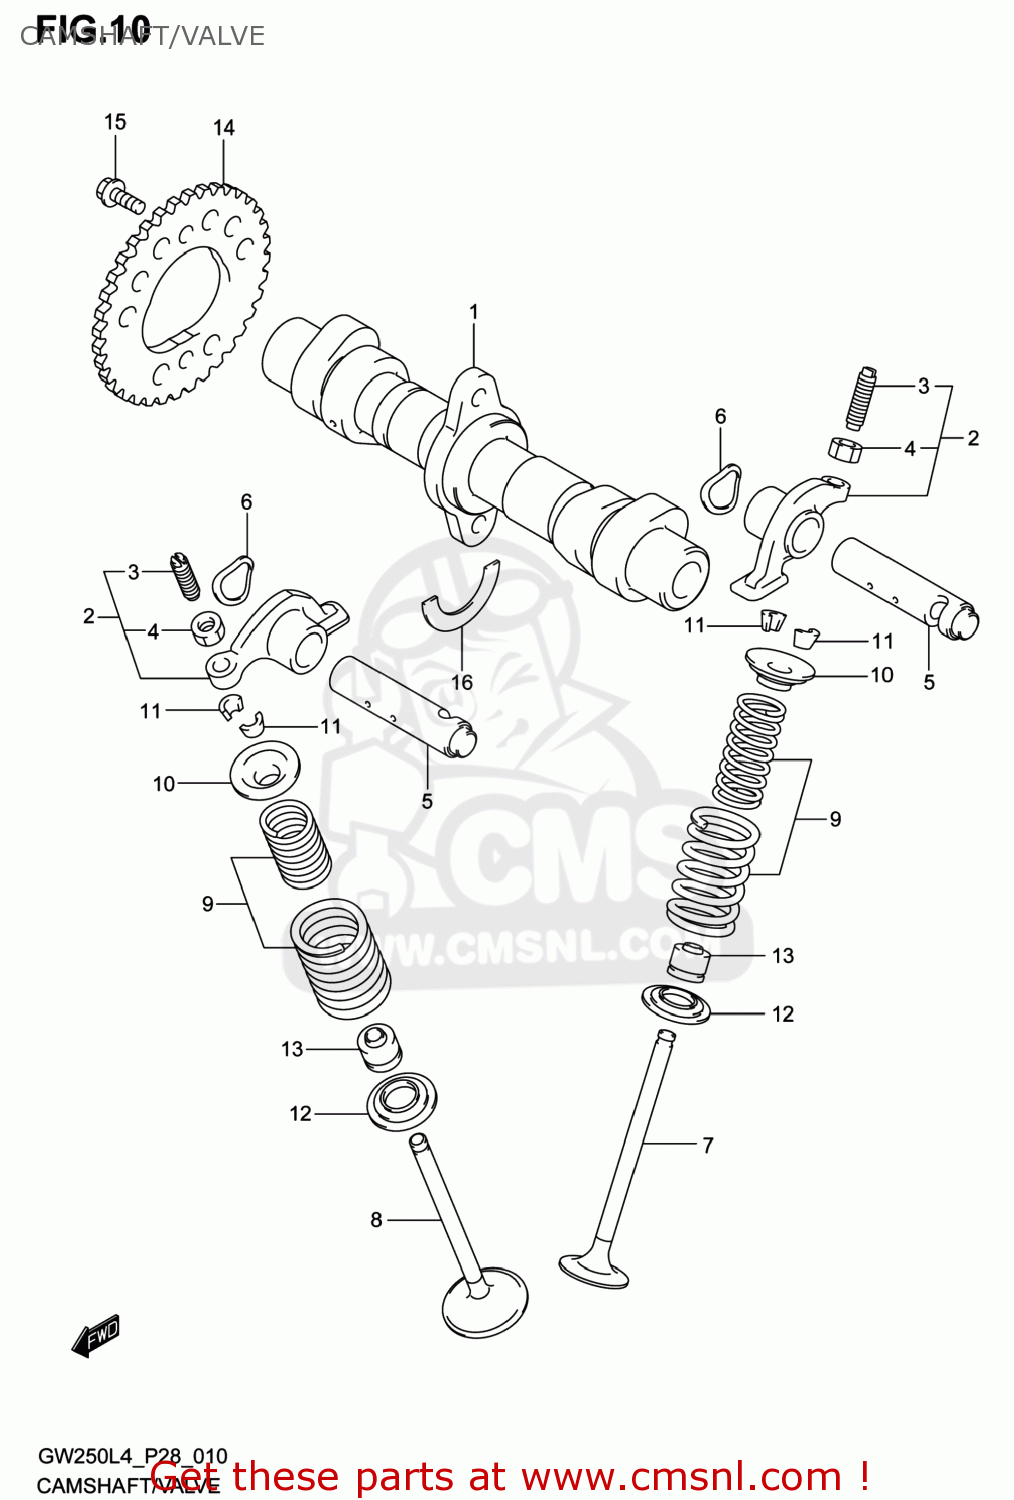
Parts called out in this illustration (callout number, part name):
1	CAMSHAFT
2	ARM ASSY,VALVE ROCKER
3	SCREW,TAPPET ADJUSTING
4	NUT,TAPPET ADJUSTING
5	SHAFT,VALVE ROCKER ARM
6	WASHER
7	VALVE,INTAKE
8	VALVE,EXHAUST
9	SPRING SET,VALVE
10	RETAINER,VALVE SPRING
11	COTTER VALVE
12	SEAT,VALVE SPRING
13	SEAL,OIL(5X10X8)
14	SPROCKET,CAMSHAFT
15	BOLT(6X12.5)
16	C RING
